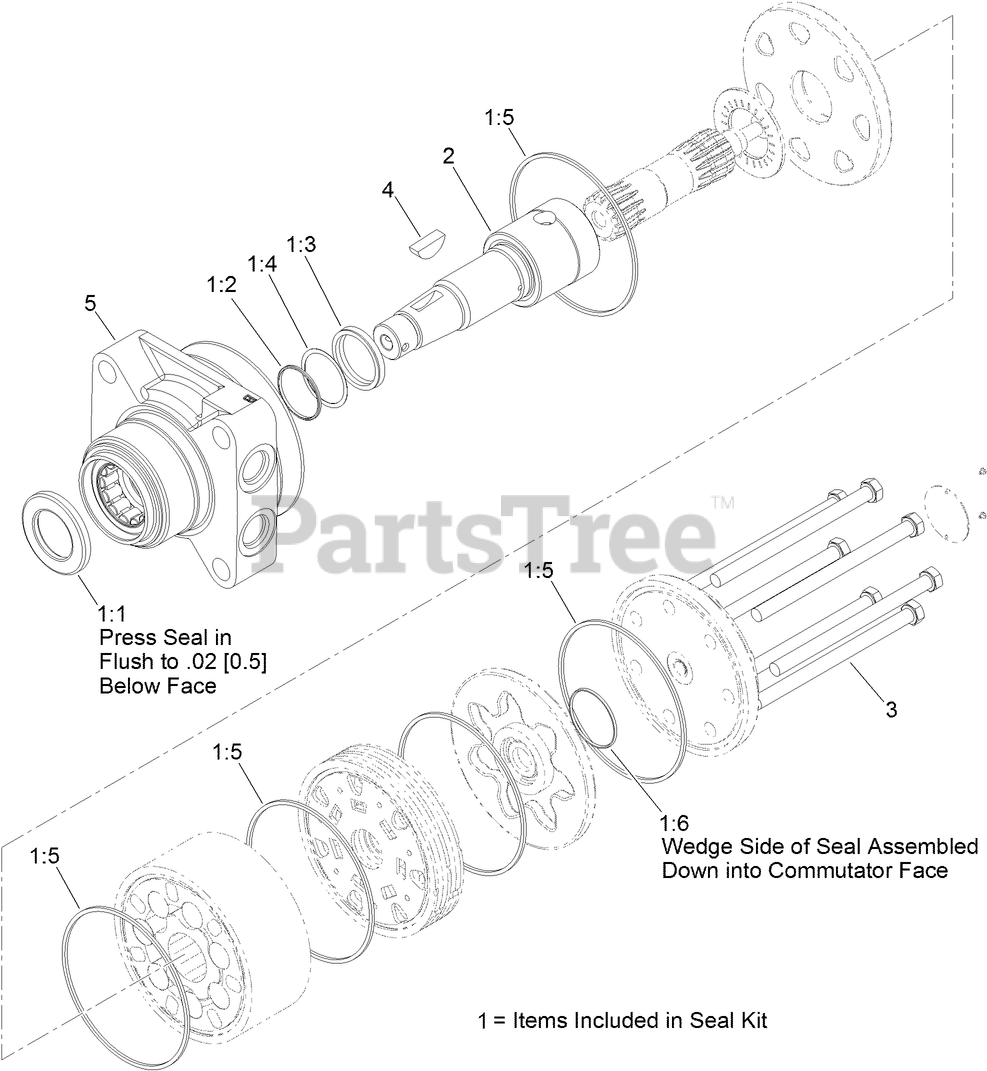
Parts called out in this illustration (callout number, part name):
1	SEAL KIT
1:1	Seal-Dirt and Water
1:2	BACKUP-RING
1:3	SEAL-SHAFT
1:4	Washer-Backup
1:5	SEAL-SQUARE, RING (INNER)
1:6	Seal-Commutator
2	SHAFT-COUPLING
3	SCREW-CAP, HH
4	KEY-WOODRUFF
5	MOTOR HOUSING ASM
